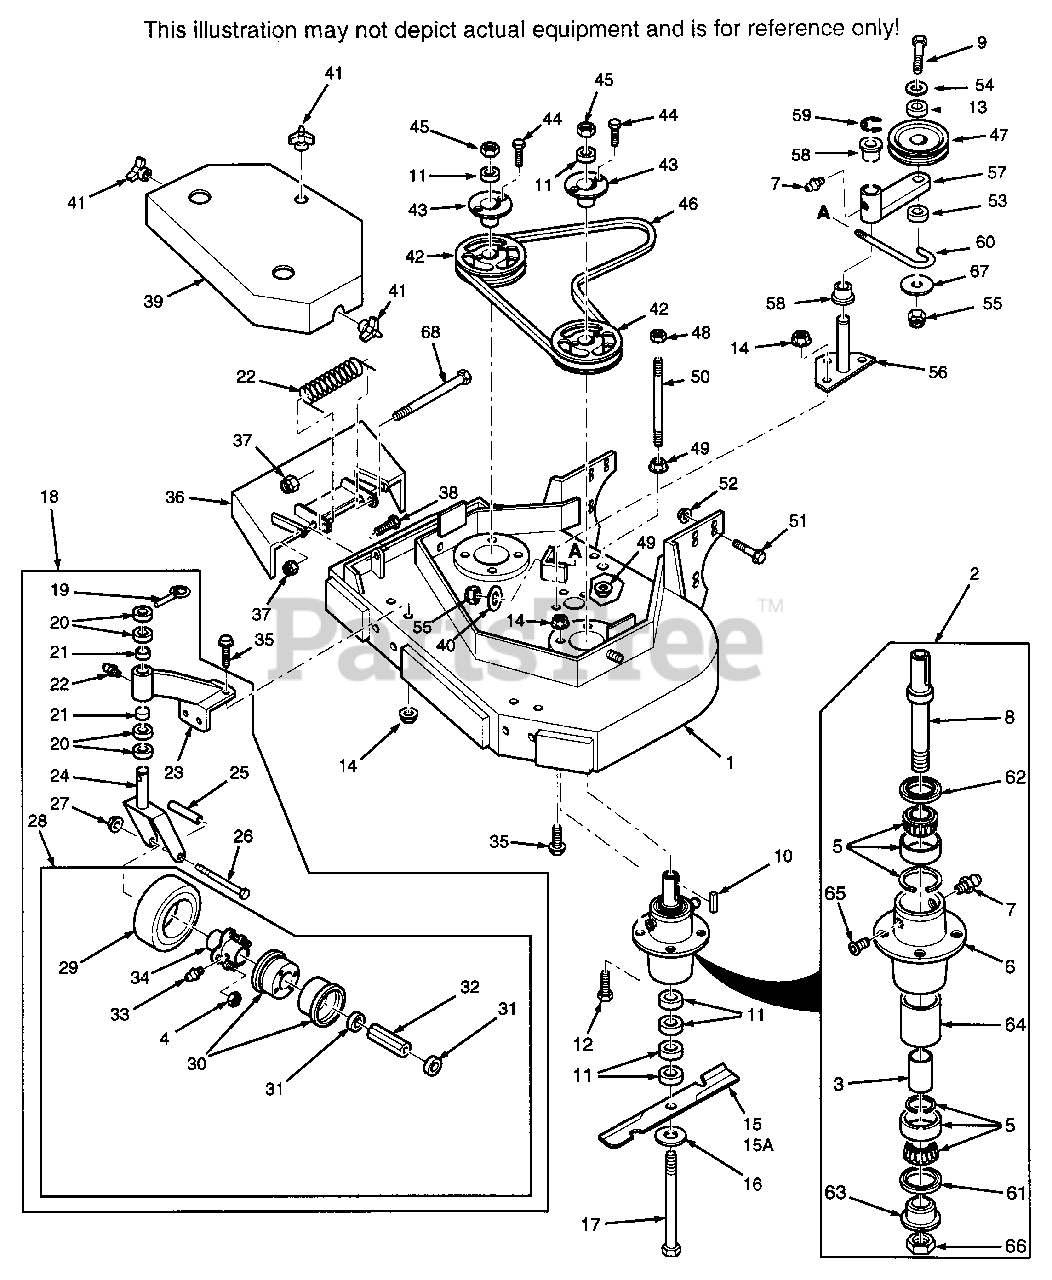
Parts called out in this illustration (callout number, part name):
1	CUTTER DECK(INCLUDES DECALS)
2	CUTTER SPINDLE ASSEMBLY
3	SPACER, INSIDE
4	TAPERED NUT, 5/16-24
5	TAPERED BEARING(TWO)
6	SPINDLE HOUSING, TAPERED BEARING
7	GREASE FITTING STR. 5/16
8	SPINDLE SHAFT
10	KEY, 1/4 X 2"
11	SPACER, CUTTER BLADE
12	HEX HEAD BOLT, 5/16-18 X 1-1/4"
13	SPACER
14	NUT, 5/16-18 SERRATED FLANGE
15	CUTTER BLADE, 18"
15A	CUTTER BLADE, 18" HIGH LIFT
16	FLAT WASHER, 5/8" W
17	HEX HD. BOLT, 5/8-11 X 9-1/2"
18	CASTER ASSEMBLY(INCLUDES 19-28)
19	QUICK PIN
20	SPACER, CASTER YOKE, 1/2" THICK
21	BRONZE BEARING
22	SPRING, CHUTE RETURN
23	SUPPORT ASSY.(INCL. 21-23)
24	CASTER YOKE
25	SLEEVE, CASTER WHEEL BEARING
26	HEX HD. BOLT, 1/2-13 X 5-1/2"
27	HEX LOCKNUT, 1/2-13
28	WHEEL ASSY.(INCL. 4,29-34)
29	TIRE ONLY, CASTER WHEEL
30	RIM PAIR, CASTER WHEEL
31	RETAINER, BEARING, CASTER WHEEL
32	ROLLER BEARING, CASTER WHEEL
33	GREASE FITTING 45 DEG., 1/4-28
34	HUB ASSY.(INCL. BOLTS)
35	CAPSCREW, 5/16-18 X 3/4" SERR. FLANGE HEX
36	DISCHARGE CHUTE
37	HEX NUT, 5/16-18 ELASTIC STOP
39	BELT COVER ASSEMBLY
40	FLAT WASHER, 3/8"(.391 X .938 X .105)
41	WING NUT, 3/8-16
42	PULLEY
43	TAPERED HUB, 1.125 BORE
46	BELT, BLADE DRIVE
47	PULLEY, BELT GUIDE
48	HEX NUT, CENTER LOCKNUT
49	NUT, 3/8-16 SERRATED FLANGE
50	SUPPORT, BELT COVER
51	CAPSCREW, 7/16-14 X 1" SERR. FLANGE
52	HEX NUT, 7/16-14 SERRATED FLANGE
53	SPACER, J-HOOK
54	FLAT WASHER
55	NUT, 3/8-16 ELASTIC STOP
56	IDLER PIVOT
57	IDLER ARM ASSY.(INCL. 22 & 58)
58	BUSHING, 1-1/8 X 1.0 FLANGED
59	RETAINING RING, 1-1/8" EXT. "E"
60	J-HOOK
61	SEAL, CUTTER SPINDLE
62	SEAL, CUTTER SPINDLE
63	SPINDLE BUSHING
64	SPACER, OUTSIDE
65	RELIEF FITTING, CUTTER SPINDLE
67	FLAT WASHER
